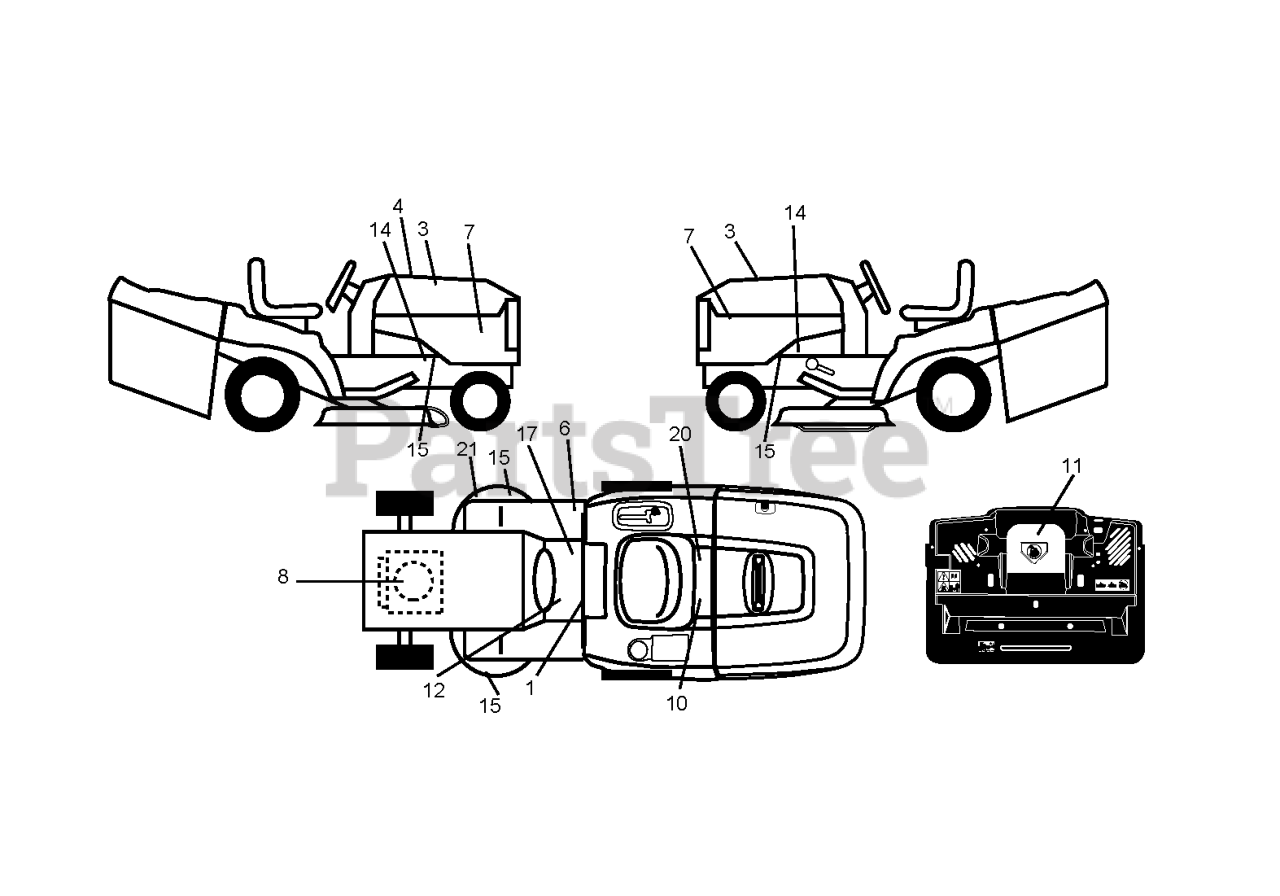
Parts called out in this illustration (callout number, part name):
1	LABEL
3	DECAL.HOOD.NAMELOGO.HUSQ
6	Decal, Fender 100 DB/CE
8	DECAL
10	DECAL BTRY SYMBOLS
11	DECAL.INTERNATIONL.CUTFINGER
12	DECAL
17	DECAL PARK BRAKE
20	DECAL.BYPASS.FENDER.CRD.LT.YT
